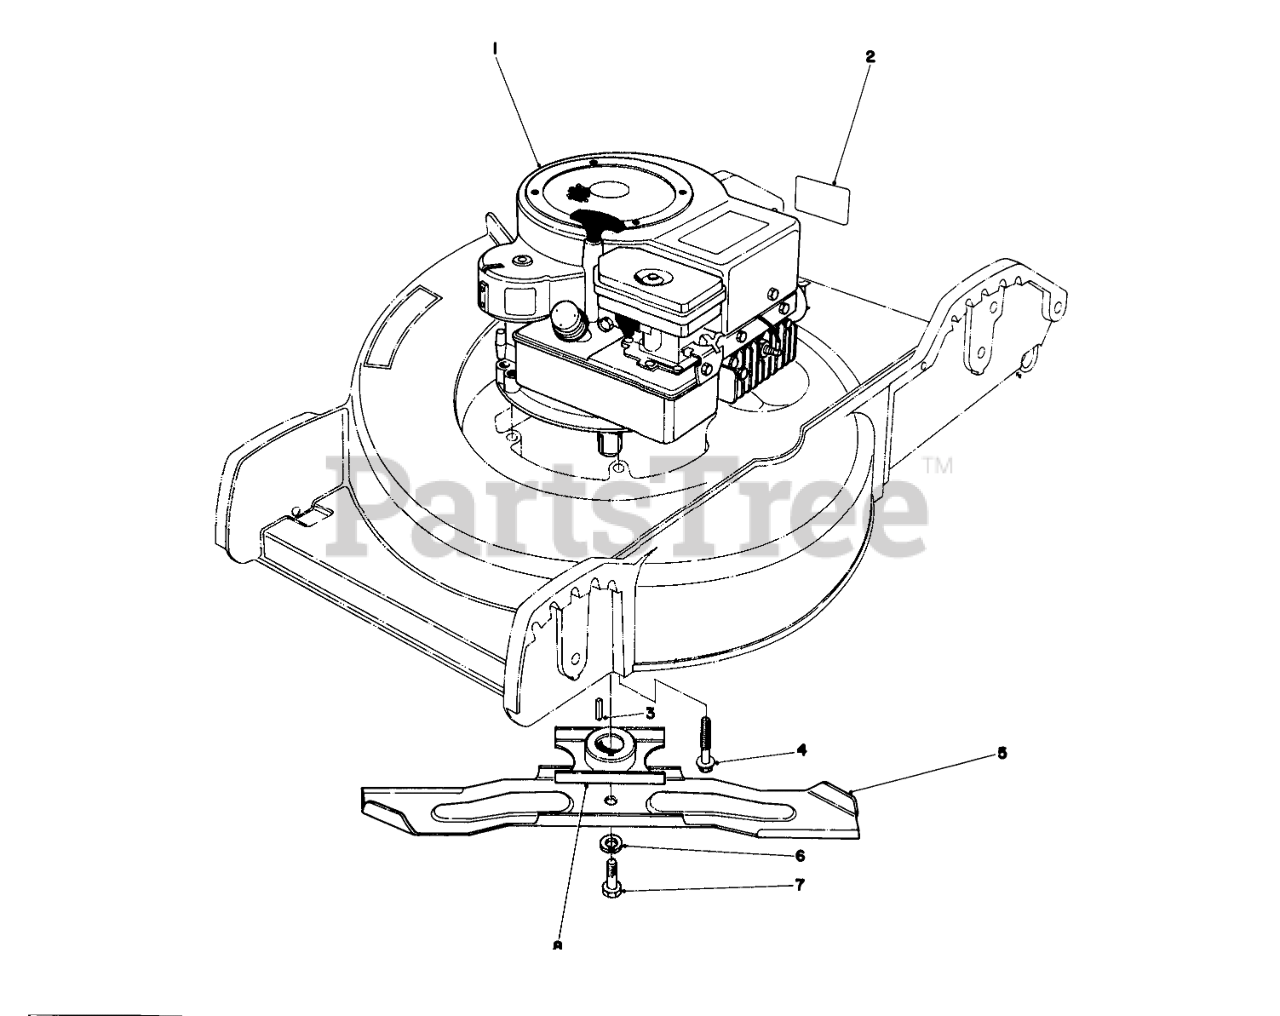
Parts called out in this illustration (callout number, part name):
1	Engine
2	Decal Maintenance
3	Key-Square
4	3/8-16 X 2 CAPSCREW
5	Blade
6	WASHER-LOCK
7	SPECIAL SCREW
8	Blade Retailer
